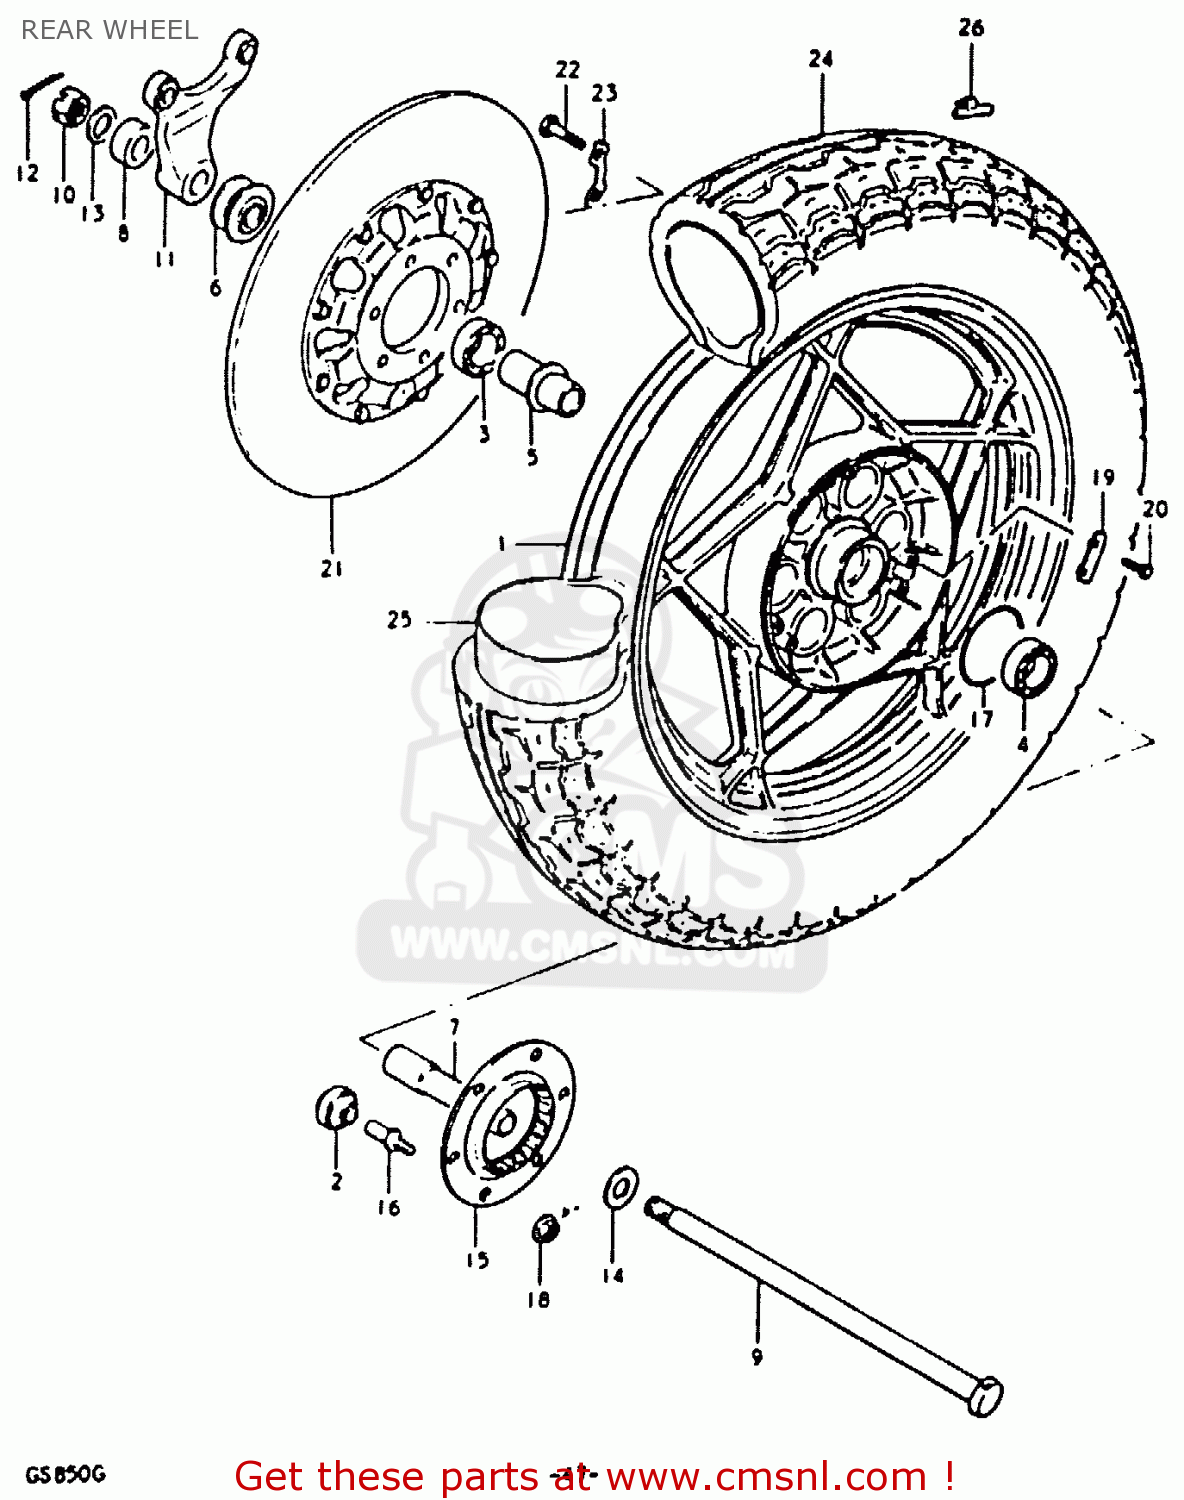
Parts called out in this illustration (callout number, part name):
1	CASTING WHEEL,REAR
2	BUSH
3	BEARING
4	BEARING
5	SPACER,REAR HUB BEARING
6	SPACER,REAR AXLE
7	SPACER,REAR AXLE,LEFT
8	SPACER (17X33X15.2)
9	AXLE,REAR
10	NUT
11	BRACKET,RR,CALIPER
12	PIN,COTTER
13	WASHER
14	WASHER (17.5X36X3.2)
15	JOINT, DRIVEN
16	BOLT
17	O RING(D:2.1,ID:65)
18	NUT
19	WASHER
20	BOLT, UPPER
21	DISC,BRAKE
22	BOLT(8X30)
23	WASHER
24	TIRE
25	TUBE ASSEMBLY,WHEEL,INNER
26	BALANCER,WHEEL
